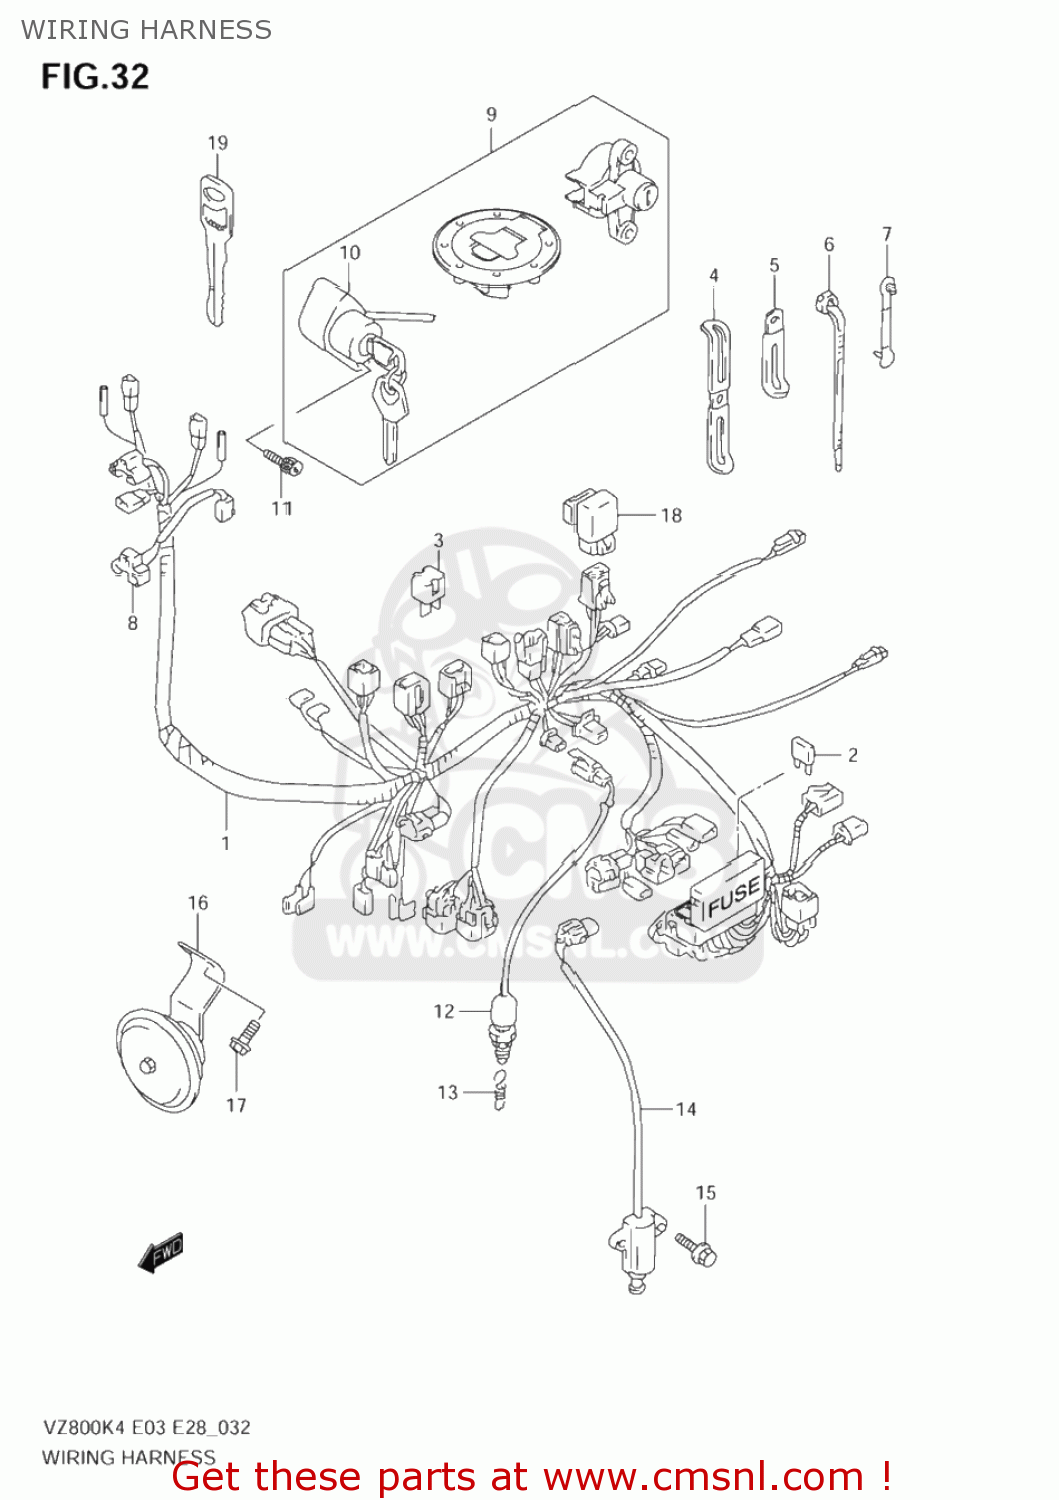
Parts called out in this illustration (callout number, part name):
1	HARNESS,WIRING
2	FUSE(10A)
3	RECTIFIER ASSY
4	CLAMP,STARTER MOTOR LEAD
5	CLAMP(L:45)
6	CLAMP(L:125)
7	CLAMP(L:33)
8	LEAD WIRE,HEADLAMP
9	LOCK SET
10	SWITCH ASSY,IGNITION
11	BOLT(6X15)
12	SWITCH ASSY,STOP LAMP
13	SPRING
14	SWITCH ASSY,SIDE STAND WARNING
15	BOLT
16	HORN ASSY
17	BOLT
18	RELAY ASSY
19	KEY,BLANK
